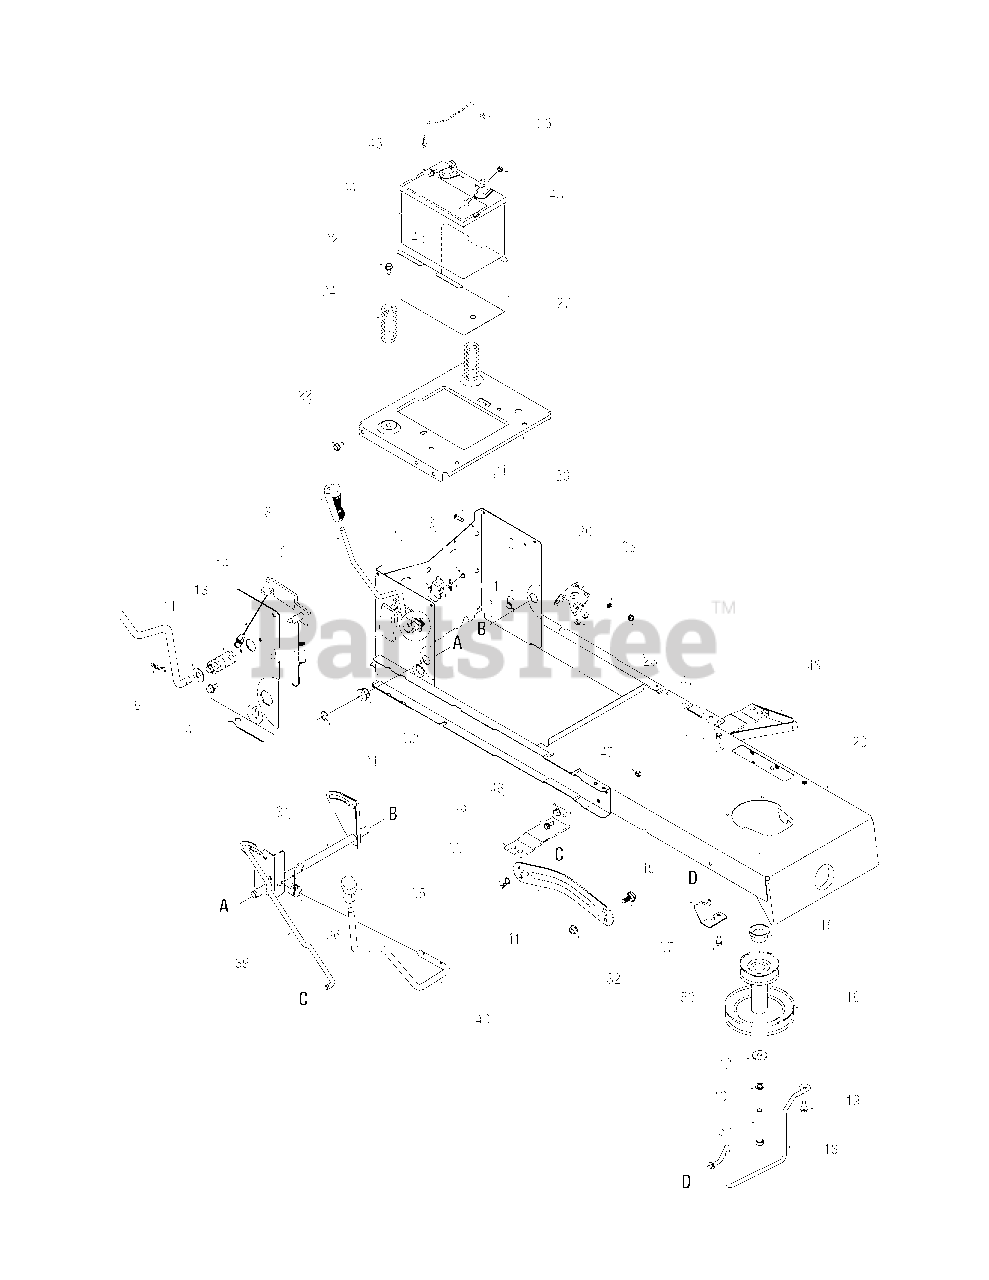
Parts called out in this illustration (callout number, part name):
1	Plate, Switch
3	Screw, #10-16, 0.500
4	Screw, 1/4-20, 0.500
5	Screw, 7/16-20, 3.25, Gr5
6	Pin, Cotter, .072 Dia. x 1.13
7	Pin, Click, .092 x 1.64
8	Grip, Handle, 3/8
9	Spring, Extension
10	Washer, Lock, 7/16
11	Washer, Flat, .406 x .875 x .059
12	Washer, Flat, .450 x 1.250 x .164
13	Bearing, PTO
14	Cable, Deck Engagement
15	Spacer, 1.010 x 1.400 x .825
16	Engine Pulley, 3.56 x 6.12 Dia.
17	Switch, Interlock
18	Rod, Belt Keeper (38-inch Deck)
18	Rod, Belt Keeper (42-inch Deck)
19	Screw, 5/16-18, .750
21	Screw, 1/4-20, 0.750
22	Screw, 5/16-18, 0.625
23	Nut, Flange Lock, 1/4-20, GrF, Nylon
24	Spring, Compression, 1.28 OD x 3.125
25	Washer, Lock, 1/4
30	Solenoid
32	Nut, Flange Lock, 3/8-16, GrF, Nylon
33	Pin, Cotter, .080 x 1.5625 Internal
34	Ring, E-Type, .625 Dia.
35	Grip, Handle, 1/2
36	Spring, Torsion
37	Screw, Shoulder, .625 x .175, 3/8-16
38	Bearing, Hex Flange
39	Rod, Lift
40	Deck Handle, Lift
42	Screw, Carriage, 1/4-20, .75, Gr5
43	Nut, Sems, 1/4-20
44	Battery, 190 CCA (Single Cylinder Engine)
44	Battery, 270 CCA (Twin Cylinder Engine)
45	Screw, Shoulder, .250 x .150, 1/4-20
46	Screw, 5/16-18, 0.750
47	Nut, Hex Lock, 5/16-18, Nylon
50	Screw, 5/16-18, 0.625, Gr5
